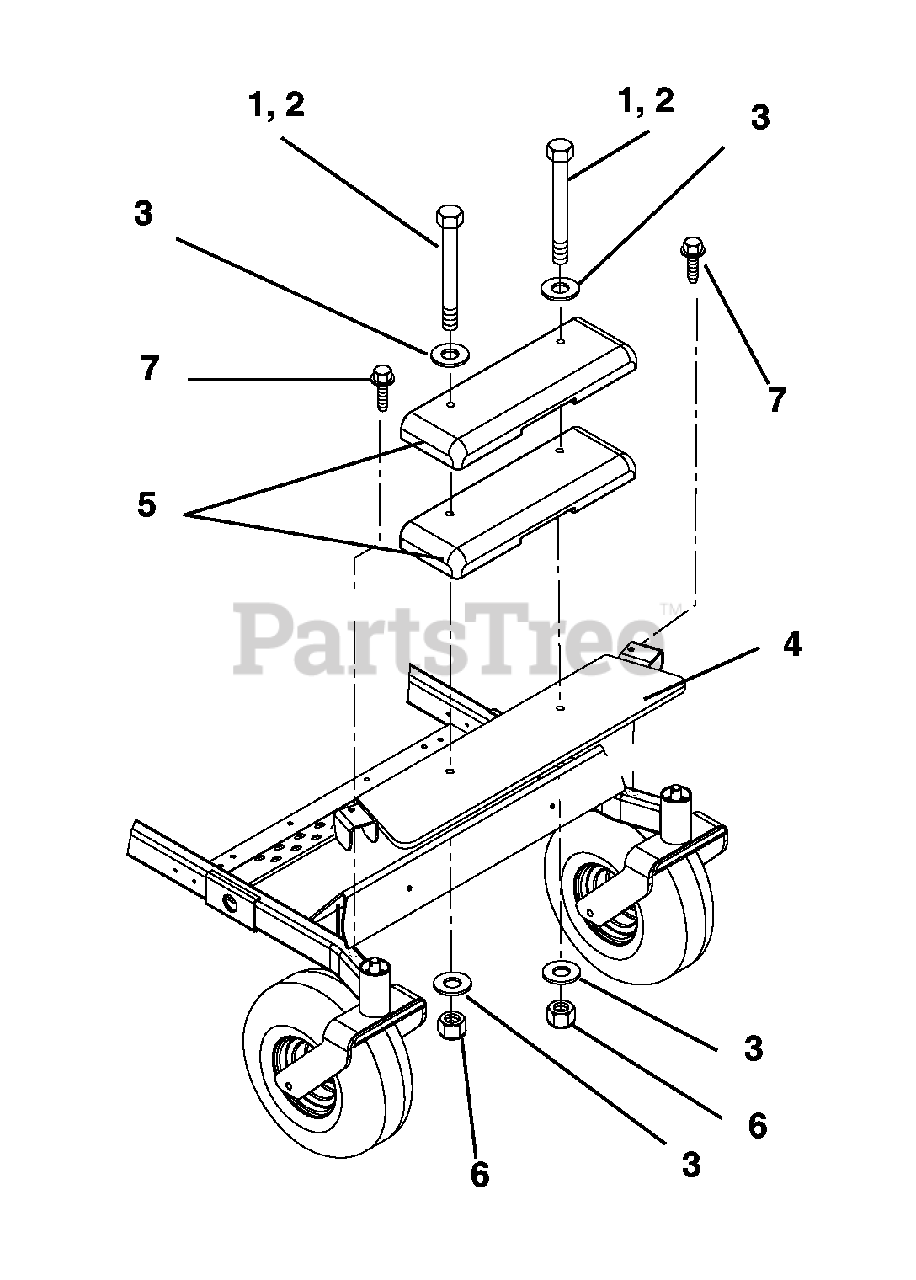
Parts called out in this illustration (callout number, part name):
1	Bolt-Hex .50-13 x 7.50 Grade 5
2	Bolt-Hex .50-13 x 5.50 Grade 5
3	Washer-Flat-Steel .51 x 1.00 x .062
4	Weldment, Weight Plate
5	Counterweight
6	Nut-Locking-Center .50-13
7	Tapping Screw, 3/8'-16 x 1/2'(892016)
